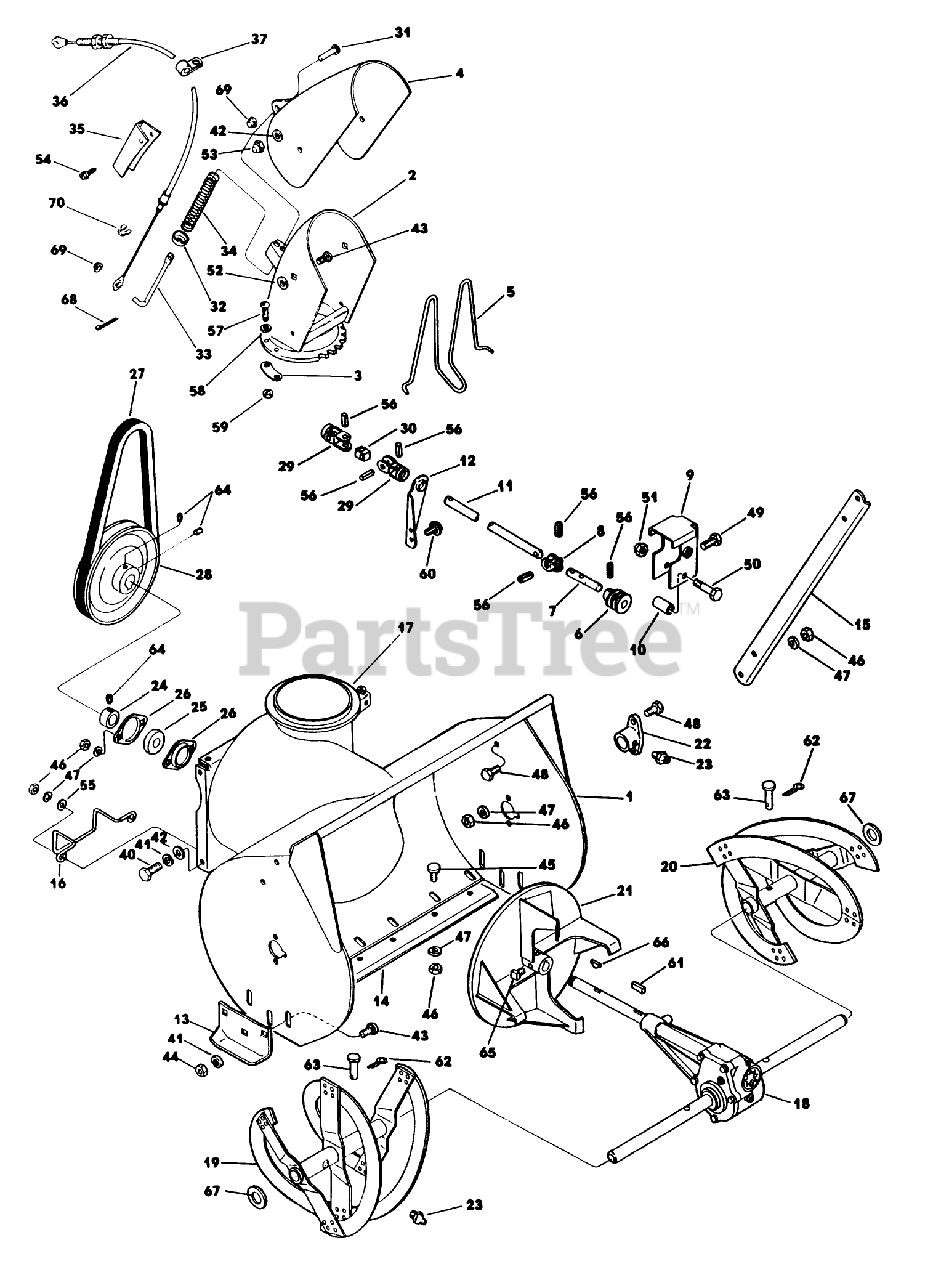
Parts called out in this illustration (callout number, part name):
3	HOLD DOWN CHUTE
14	SCRAPER
16	LWR AUGER BELT GUIDE
21	IMPELLER ASSEMBLY (12)
25	DISCONTINIUED
26	FLANGETTE-BEARING
28	PULLEY ASM
30	PIVOT PIN
48	SCREW - HEX
51	NUT-LOCK, CONE
53	NUT-LOCKING
54	SCREW S
58	WASHER - LOCKING
60	SCREW-HWH
63	PIN-CLEVIS
64	SET SCREW
70	RET. RING
